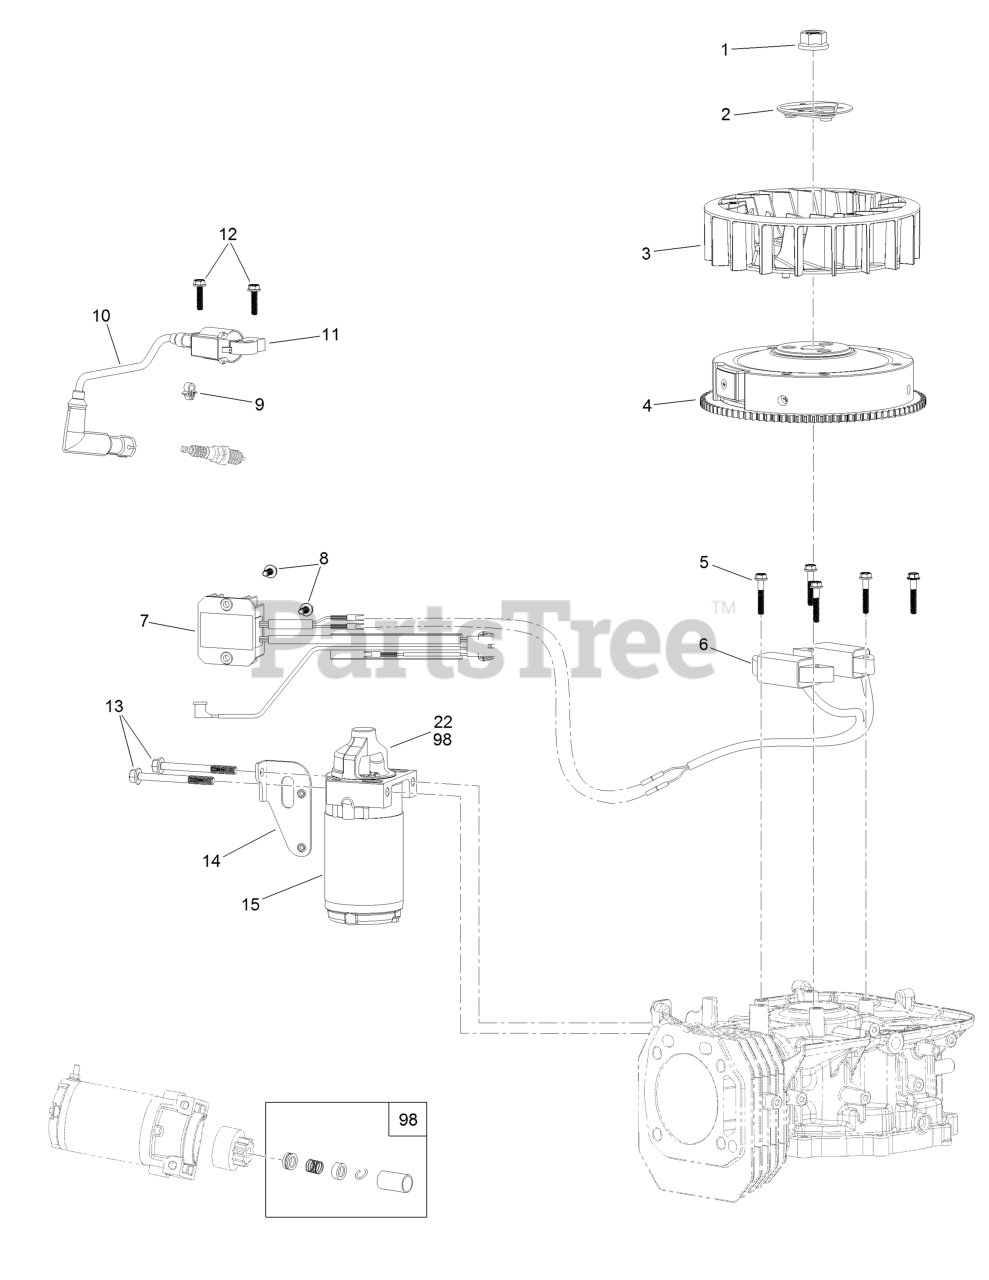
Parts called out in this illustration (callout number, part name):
1	NUT-FLANGE
2	PULLEY-STARTER
3	FAN-COOLING
4	FLYWHEEL
5	SCREW-HHF
8	SCREW-HHF
9	CLAMP-WIRE
10	BOOT-PLUG, SPARK
12	SCREW-HHF
13	SCREW-HHF
14	BRACKET-STARTER
15	MOTOR-STARTER
22	PINION-STARTER
98	STARTER REPAIR KIT
